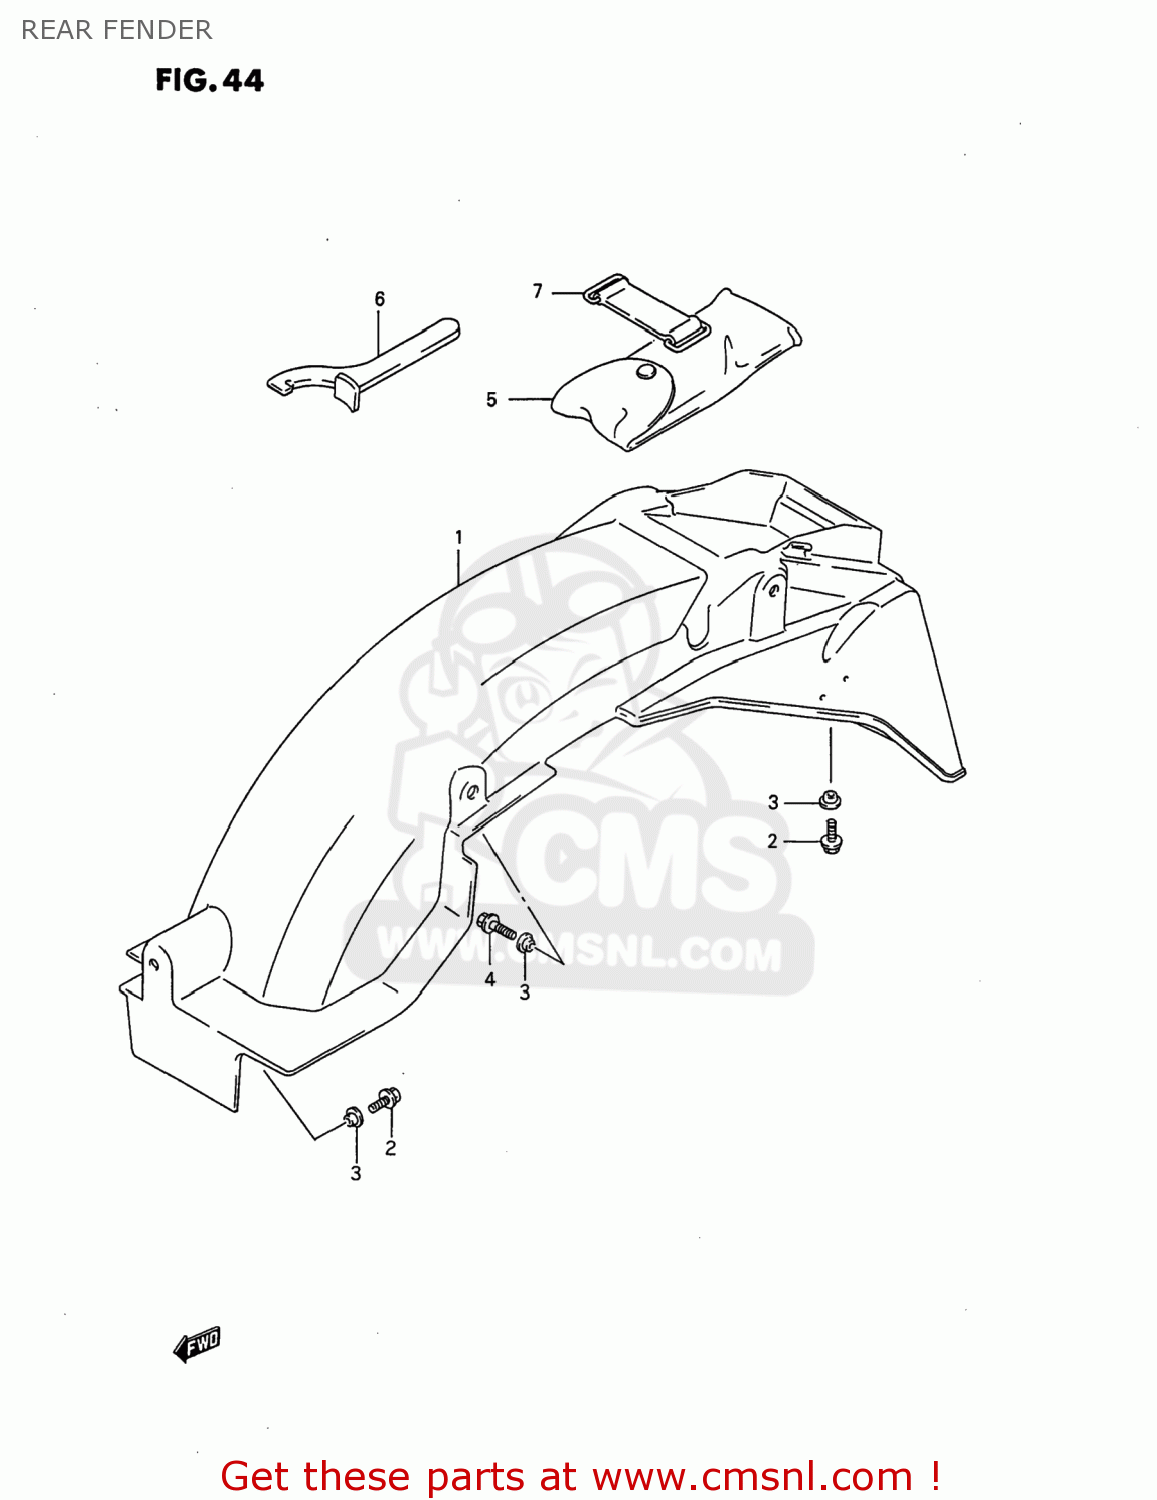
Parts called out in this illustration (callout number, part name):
1	BODY,RR FENDER
2	BOLT
3	WASHER
4	BOLT
5	TOOL ASSY
6	CLAMP
7	BAND
